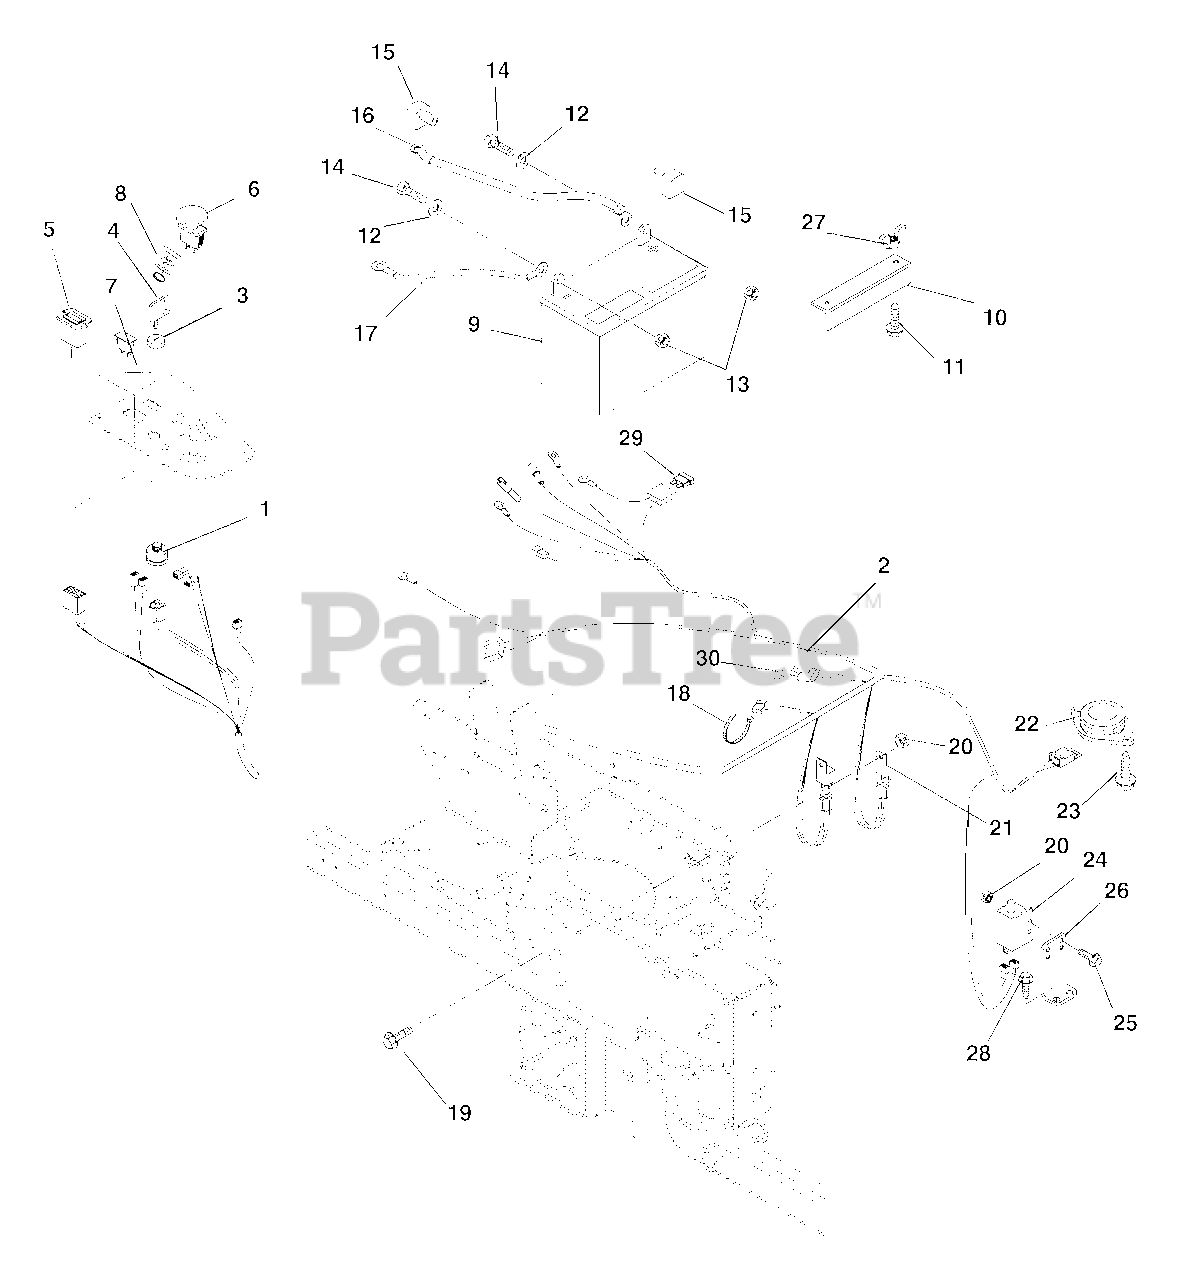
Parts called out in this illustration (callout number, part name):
1	Key Switch
2	Harness, Z 6-Pin Wiring
3	Cap-Ignition Switch
4	Key with Shield
5	Hour Meter
6	Switch-Clutch With Retainer Ring
7	Light-Indicator Kit
8	Key Chain
10	Hold Down
11	Bolt, Round Head Square Neck .25-20 x 7.00 Grade 2
12	Washer-Flat-Steel .281 x .620 x .065
13	Nut-Locking-Top-Flange .25-20
14	Bolt-Hex .25-20 x .75 Grade 5
15	Insulator
16	Positive Cable 22"
17	Ground Cable
18	Cable Tie
19	Screw-Machine 10-24 x .50 Hex Washer Head
20	Nut-Locking-Nylon 10-24 With Insert
21	Relay
22	Seat Switch
23	Screw-Tapping 12-24 x .50 Hex Washer Head
24	Switch-Single Pole
25	Screw-Machine 10-24 x .75 Hex Washer Head
26	Mount, Brake Switch
27	Nut-Locking Wing .25-20
28	Screw-Tapping .25-20 x .50 Hex Washer Head
29	Fuse, 30 Amp
30	Molded Diode Plug-Black 1-Amp
